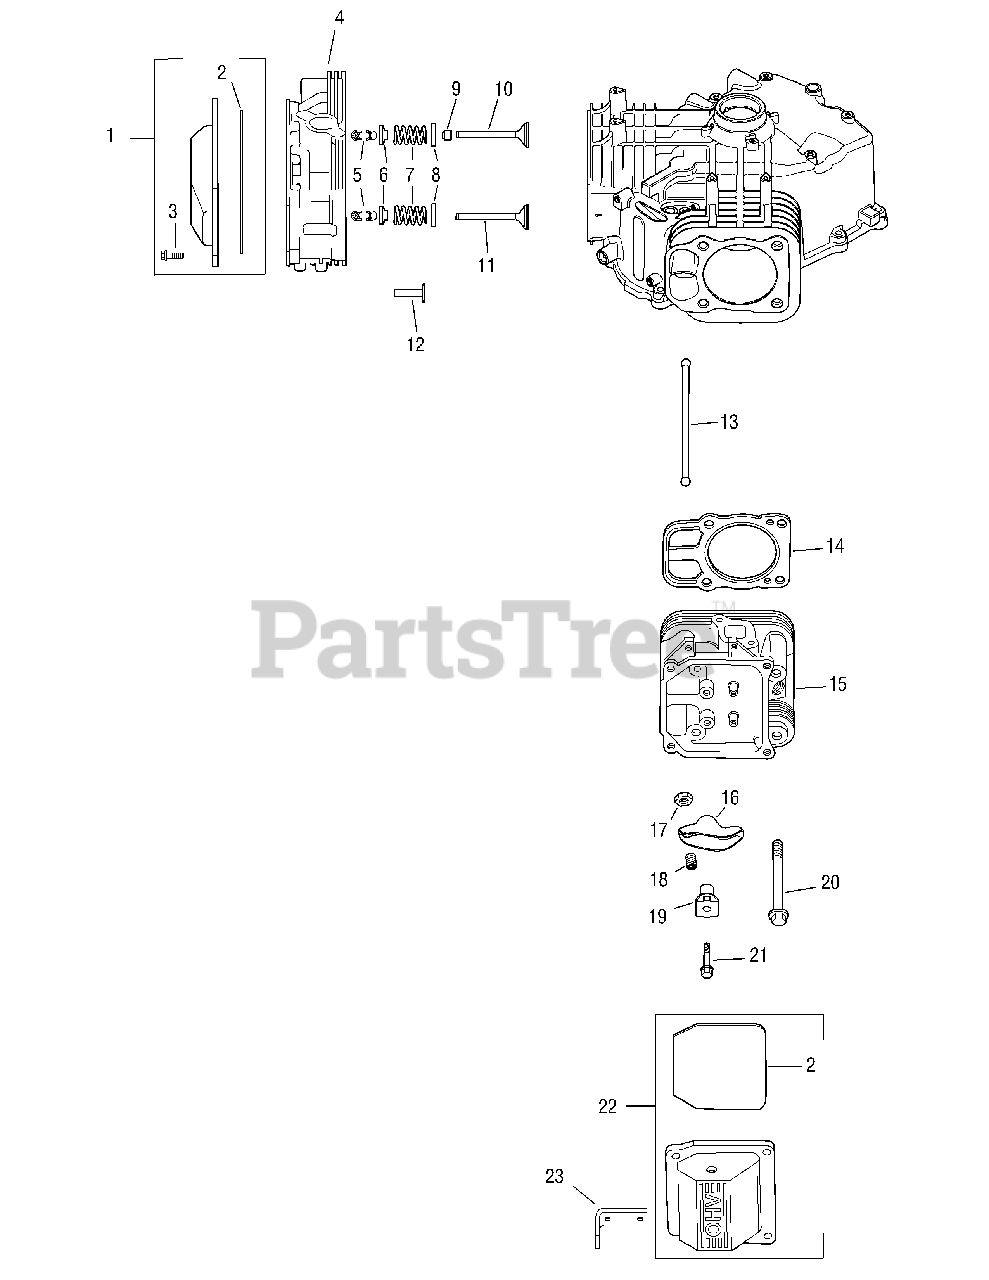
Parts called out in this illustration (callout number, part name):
1	Kit, valve cover (Includes 2,3)
2	O-Ring
3	Screw, hex. flange M6x1.0x30
4	Head assembly, #1 cylinder
5	Kit, retainer
6	Cap, valve spring
7	Spring, valve
8	Retainer, spring
9	Seal, valve stem
10	Valve, intake (Std.)
10	Valve, intake (.25)
11	Valve, exhaust (Std.)
11	Valve, exhaust (.25)
12	Tappet
14	Kit, cylinder head gasket
15	Head assembly, #2 cylinder
16	Arm, rocker
17	Nut, hex. M10x0.75
19	Pivot, rocker arm
20	Screw, hex. flange M10x1.5x90
21	Screw, hex. flange M6x1.0x45
22	Kit, valve cover - breather (Includes 2)
23	Strap, lifting
